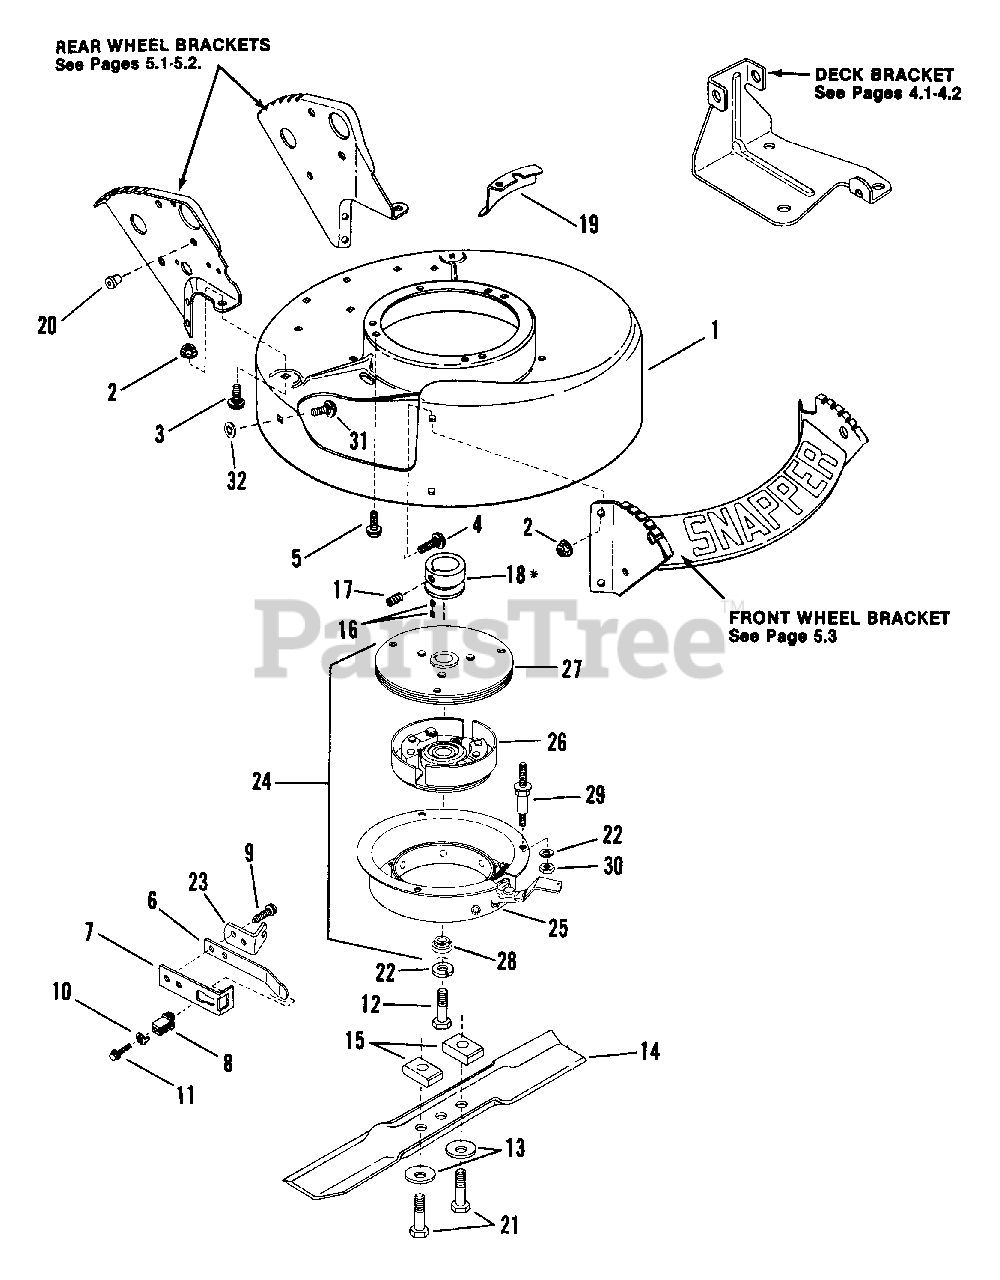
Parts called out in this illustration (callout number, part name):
1	DECK, Mower
2	NUT, Hex Flanged Lock
3	BOLT, 5/16-18 x 1/2" Short Neck Carriage Gr. 5
4	BOLT, 5/16-18 x 1" Short Neck Carriage
5	SCREW,3/8-16 x 1" Hex Head Self-tapping
6	SPRING, Wheel Bracket Type Interlock
7	BRACKET, Wheel Bracket Type Interlock
8	INSULATOR, Interlock
9	SCREW, 1/4-20 x 1/2" Hex Self-tapping
10	WASHER, No. 8 TAB Int. Tooth Lock
11	SCREW, No. 8-18 x 3/4" Hex Head Machine
12	SCREW, 3/8-24 x 2.0" Hex Head Cap
13	WASHER, Cone
14	BLADE, Cutter, (Robin)
14	BLADE, Cutter (B&S)
15	SPACER, Blade
16	KEY, Hi-Pro
17	SCREW,5/16-18 x 5/16" Hex Socket Set
18	PULLEY, Engine
19	SHIELD, Cover, Belt Opening
20	BUSHING, Interlock Wire
21	SCREW, 3/8-16 x 1-3/4" Hex Head Cap
22	WASHER, 3/8 Split Lock
23	BRACKET, CABLE - BBC
27	ASSEMBLY, Flywheel (7/8")
28	WASHER, Blade
29	STAND-OFF
30	NUT, 3/8-16 Hex Flange Lock
31	BOLT, 5/16-18x1" Short Neck Carriage
32	RETAINER, 5/16 Bolt
